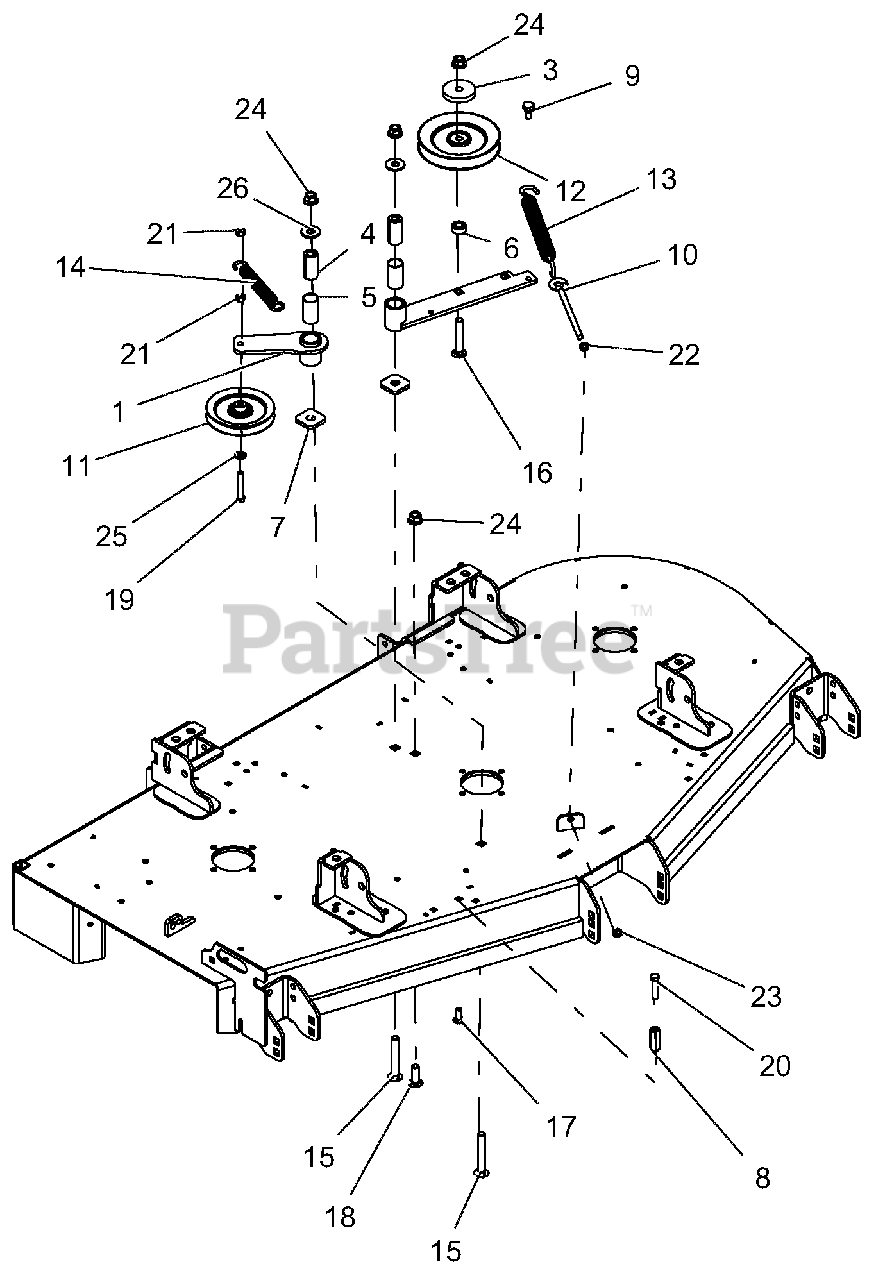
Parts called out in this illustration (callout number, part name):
1	WMT, IDLER PIVOT ARM-BLACK
3	CAP, IDLER BEARING SEALING
4	BSHG, SPCR .502X.997X2.03
5	BSHG, 1.00X1.125X1.937
6	BSHG, SPCR .502 X .997.50 PM
7	WSHR, -FLT.640X1.75X.250
8	NUT-HEX COUPLING
9	BLT, SHLDR EP .38-16X.30 HEX YZ
10	BOLT, .38-16X6.00 .62 DIA EYE
11	IDLER, V-5.00" W/.69 STANDOFF
12	SHEAVE, .50" ID X 6.00" OD V-IDLER
13	SPRG, EXTENSION
14	SPRG, EXTENSION
15	@BLT-RDHDSQNK .50-13X3.50 G5 Y
16	@BLT-RDHDSQNK .50-13X3.00 G5 Y
17	@BLT-RDHDSHSQNK.38-16X1.0 G5YZ
18	BLT-RDHDSQSHNK .50-13X1.50 YWZC
19	BLT-HEX .38-16X2.25 GR5 YWZC
20	BLT-HEX .38-16X1.75 GR5 YWZC
21	@NUT-LK-CTR .38-16 YWZC
22	NUT, JAM .375-16 YWZC
23	@NUT-LK-CTR-JAM .375-16 YWZC
24	NUT-LK-NYL-FLG .50-13 YWZC
25	@WSHR-FL-STL.406X.812X.065 YWZ
26	@WSHR-FL-STL.563X1.38X.109YWZC
